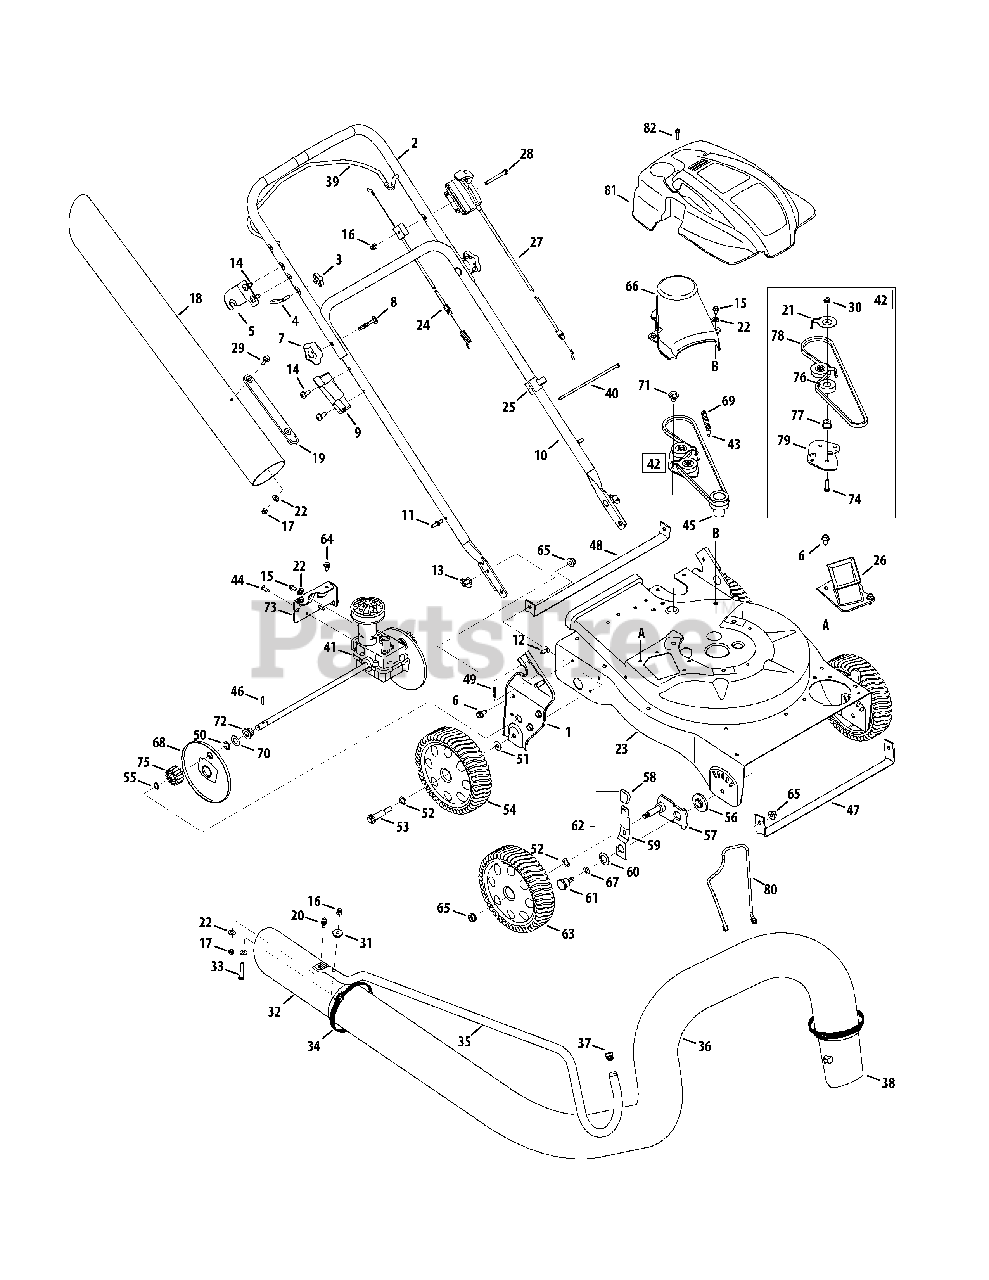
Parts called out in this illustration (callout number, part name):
1	Handle Bracket Assembly RH
2	Upper Handle
5	Upper Handle Bracket
6	Hex Cap Screw, 5/16-12 x.750
7	Handle Knob, 5/16-18
8	Carriage Bolt
9	Nozzle Handle Clip
12	Carriage Screw, 1/4-20 x.75
13	Wing Nut, 1/4-20
14	TT Screw, 5/16-18 x .750
15	Screw, 1/4-20 x .500
16	Cap Lock Nut, 1/4-20
17	Hex Lock Nut, 1/4-20
18	Hose Extension
19	Chute Strap
21	Belt Keeper
22	Flat Washer.271 ID x.630 OD
23	Upper Flail Housing
24	Drive Control Cable
25	Cable Guide
26	Chipper Chute Assembly
27	Speed Control Cable
28	Hex Screw, 1/4-20 x 2.50
29	Screw, 1/4-20 x .75
30	Flange Lock Nut, 1/4-20
32	Hose Nozzle
33	Hex Cap Screw, 1/4-20 x 2.625
34	Adjustment Clamp
36	Vacuum Hose
37	Handle Plug
38	Hose Adapter
39	Drive Control
40	Cable Tie
41	Transmission Assembly
42	Idler Assembly
43	Shoulder Screw, #12-24 x .30 x .46
44	Screw, #12-16 x .750
45	Impeller Hub
46	Dowel Pin
47	Front Wheel Support Brace
48	Rear Wheel Support Brace
49	Cotter Pin
51	Flat Washer, .406 x .875 x .105
52	Wave Washer, .531 ID x.781 OD
53	Shoulder Screw, 3/8-16
54	Wheel, 8 x 2.125
55	Snap Ring
56	Height Adjustment Bearing
57	Pivot Arm Assembly
58	Height Adjustment Knob
59	Spring Lever
60	Bell Washer, .760 ID x.25 OD
61	Shoulder Screw, .750 x.500
62	Height Lever Assembly
63	Wheel 8 x 2
64	Screw, 1/4-20 x .625
65	Flange Lock Nut, 3/8-16
66	Belt Cover
67	Thrust Washer, .375 ID x.70 OD
68	Wheel Cover
69	Extension Spring, .375 x 2.95
70	Flat Wash, .508ID x1.00OD x.020
71	Shoulder Screw, .560 x.165
72	Drive Axle Bushing
73	Transmission Mounting Bracket
74	Screw, 1/4-20 x 1.00
75	Spur Gear - RH
76	Ball Bearing
77	Flange Spacer,.260 x.659 x.517
78	Belt, 3/8 x 32.5
79	Idler Bracket
80	Tube Holder
81	Engine Shroud
82	Screw, #12-16 x 1.00
